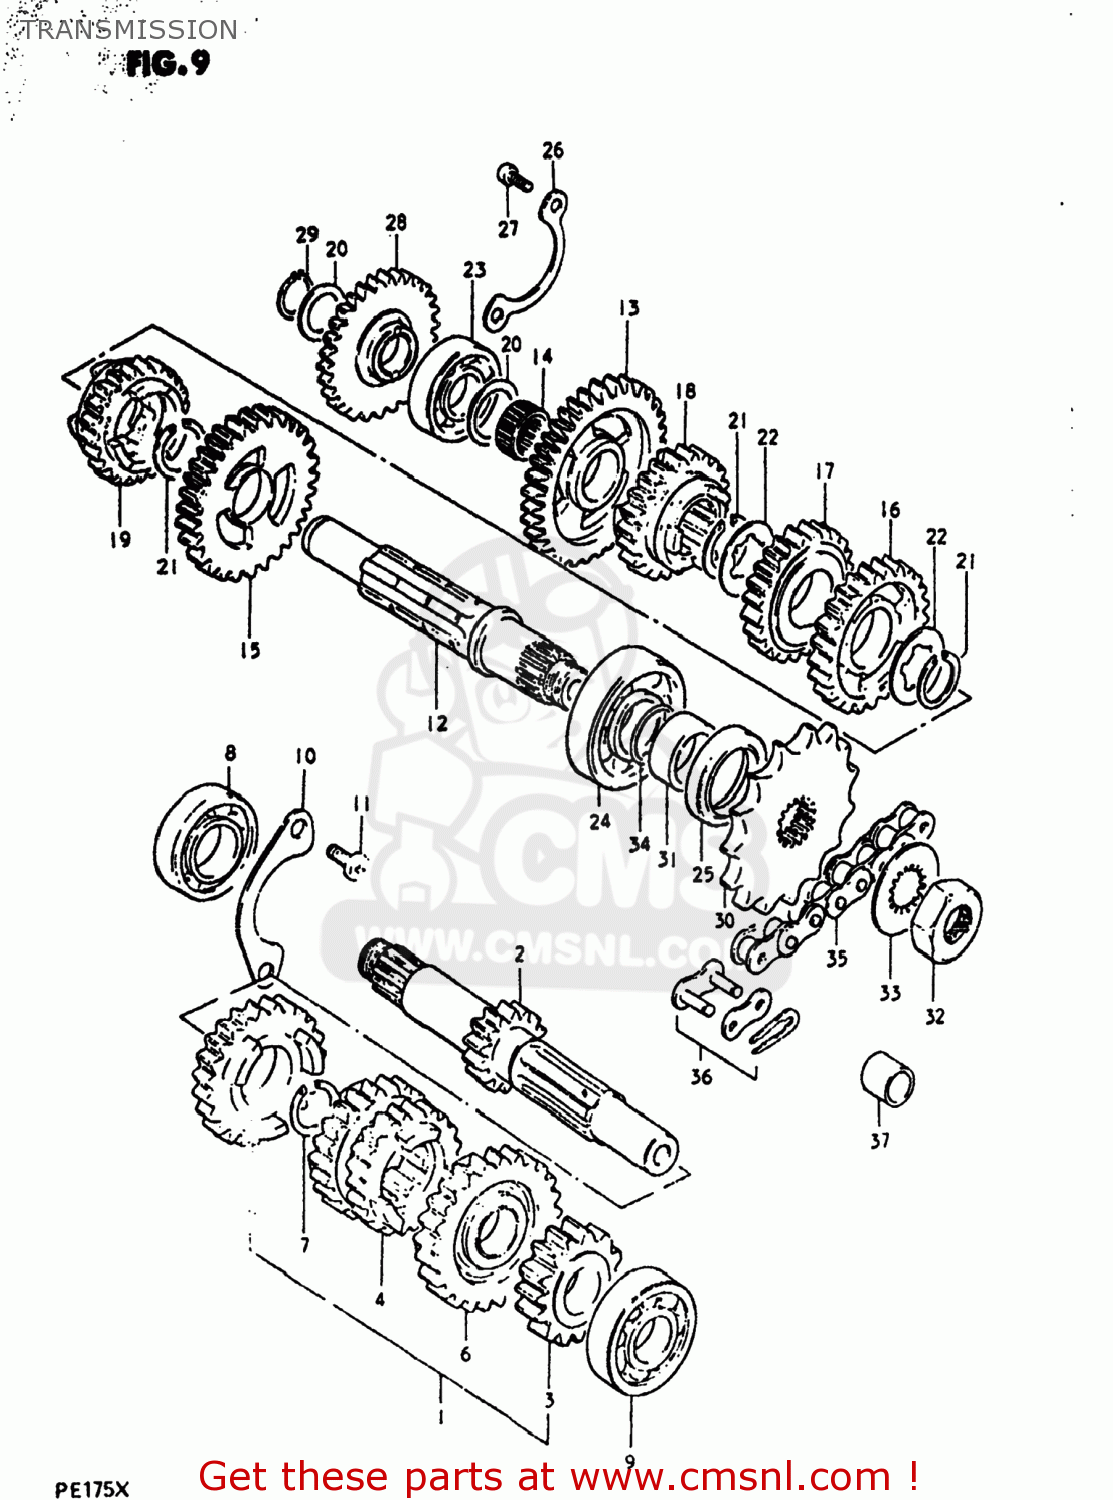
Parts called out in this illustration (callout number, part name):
1	SHAFT ASSEMBLY,COUNTER
2	SHAFT,COUNTER
3	GEAR,SECOND DRIVE
4	GEAR,THIRD DRIVE
5	GEAR,FIFTH DRIVE
6	GEAR,SIXTH DRIVE
7	CIRCLIP
8	Bearing
9	BEARING
10	RETAINER,CNTR SHAFT BEARING
11	SCREW 6X12
12	SHAFT,DRIVE
13	GEAR,FIRST DRIVEN
14	ROLLER BEARING (15X19X9
15	GEAR,SECOND DRIVEN
16	GEAR,THIRD DRIVEN
17	GEAR,FOURTH DRIVEN
18	GEAR,FIFTH DRIVEN
19	GEAR,SIXTH DRIVEN
20	WASHER,THRUST
21	CIRCLIP
22	WASHER,LOCK
23	BEARING, RH
24	BEARING(20X47X14)
25	SEAL,OIL(25X40X7)
26	PLATE,DRIVESHAFT BEARING
27	SCREW
28	GEAR,KICK STARTER IDLE
29	CIRCLIP,15MM
30	SPROCKET,ENGINE
31	SPACER(20X25X12.5)
32	NUT
33	WASHER,LOCK
34	O RING(D:1,ID:19.5)
35	CHAIN ASSEMBLY,DRIVE
36	JOINT ASSEMBLY,CHAIN
37	SPACER(12X20X15.3)
